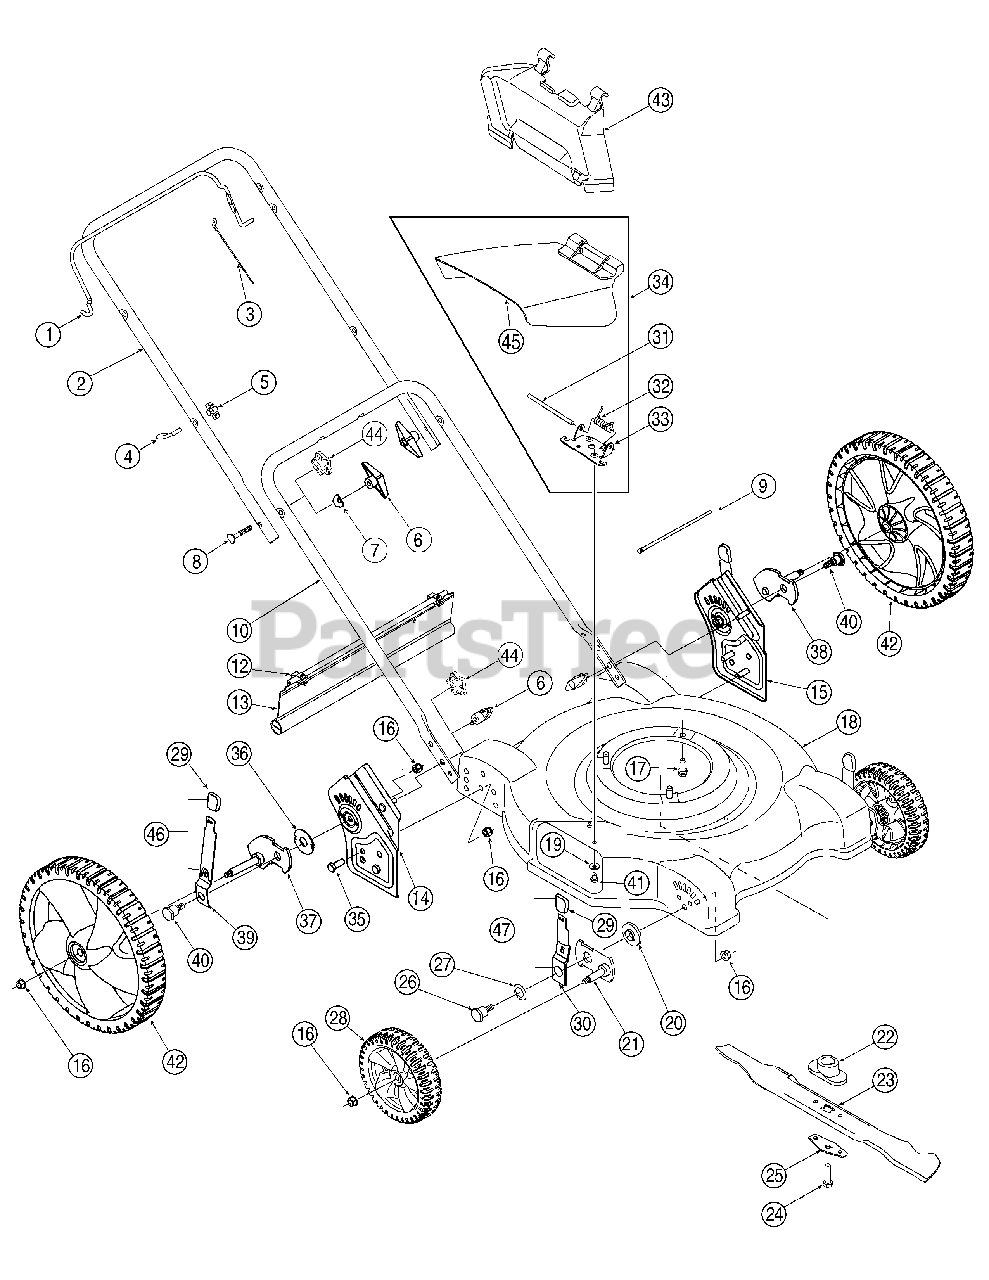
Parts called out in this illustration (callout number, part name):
3	Control Cable 48.25" Lg.
4	Rope Guide Bolt
5	Knob - ERS Guide 1/4-20
6	Handle Knob Assembly
7	Saddle Wash. .320 ID x .937 OD
8	Carriage Bolt 5/16-18 x 2.0
9	CableTie
11	Hub Cap Grey Radial
12	Hinge Clip
13	Trail Shield
17	Hex Wash HD Tap Scr 3/8-16 x .88
19	Cupp. Wash. .265 ID x .75 OD x .062
20	Height Adjuster Bearing
21	Pivot Bar
22	Blade Adapter
22	Blade Adapter 7/8 inch crankshaft
23	Mulching Blade 22"
24	Hex Screw 3/8-24 x 1.5" Lg.
25	Blade Bell Support
26	Shoulder Screw 3/8-16
27	Cupped Washer .401 ID x .870
28	Wheel Assembly Complete 7 x 1.8
29	Height Adjuster Knob
30	Spring Lever
31	Hinge Pin
32	Torsion Spring
33	Deflector Chute Adapter
34	Side Discharge Chute Assembly
35	Hex Cap Screw 3/8-16 x .75
36	Thrust Bearing .688 ID x 1.938
37	RH Rear Pivot Arm Assembly
38	LH Rear Pivot Arm Assembly
39	Rear Spring Lever
40	Shoulder Screw 3/8-16 x .442
41	Hex Wash S-Tapp Scr 1/4-20 x .50
42	Wheel Assembly 12 x 1.8 Bar Grey
43	Mulch Plug
44	Knob - Star 5/16-18
45	Chute Deflector
46	Rear Height Lever Ass'y
47	Front Height Lever Ass'y
